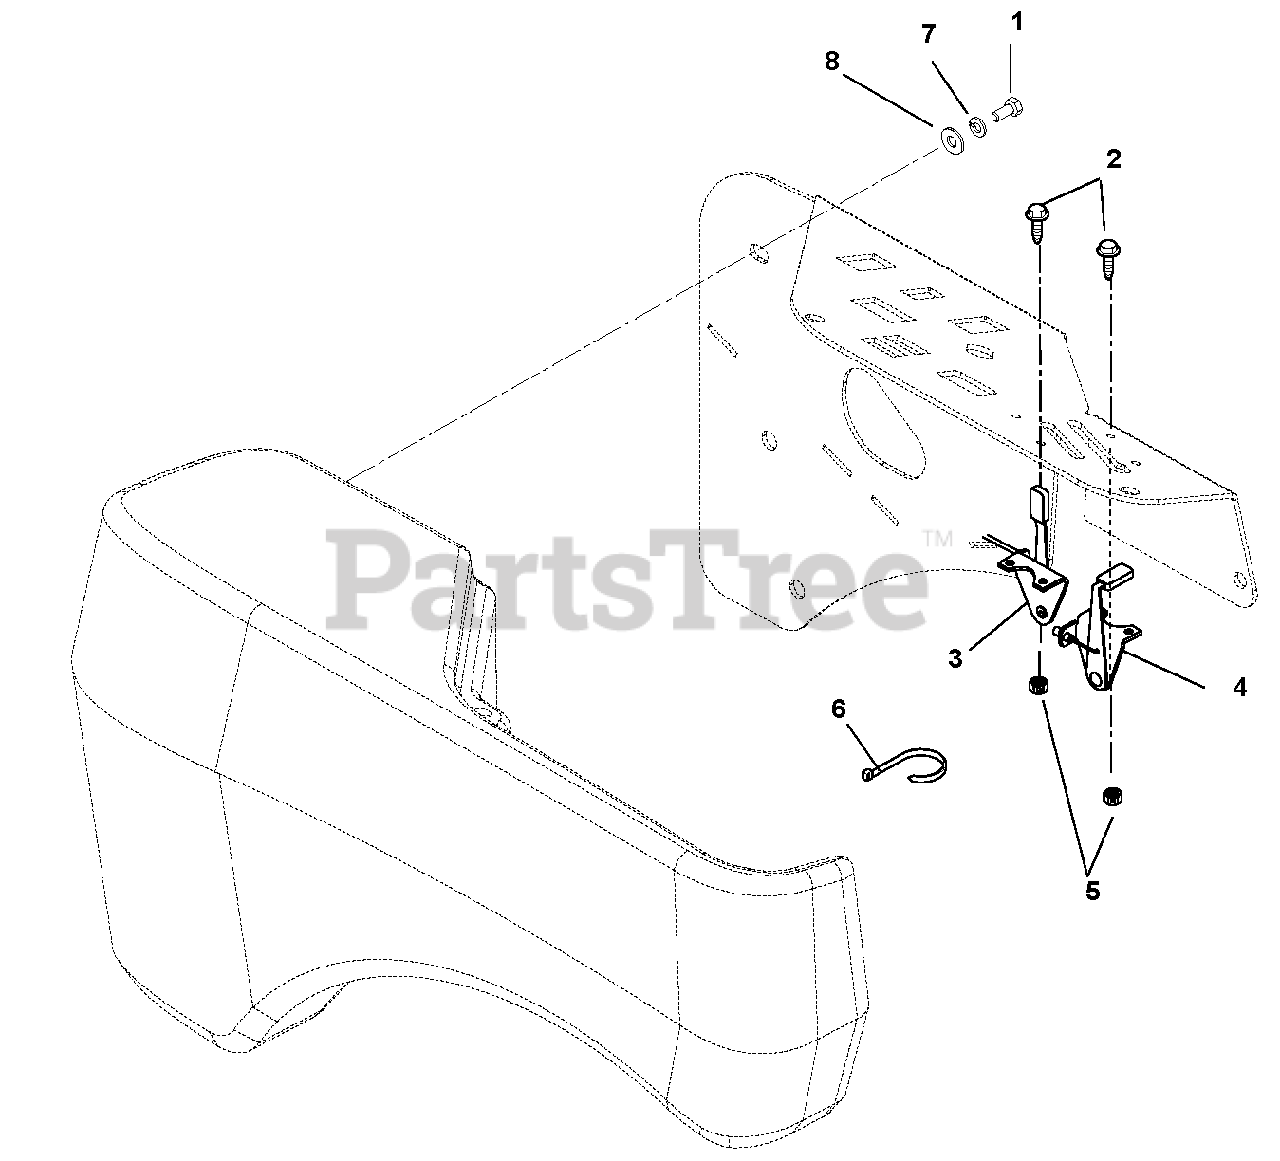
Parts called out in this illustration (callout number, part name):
1	Bolt, Hex .31-18 x .75 Grade 5 YWZC
2	Screw, Machine 10-24 x .50 Hex Washer Head
3	Cable, Kohler Throttle
4	Cable, Kohler Choke
5	Nut, Locking Nylon 10-24 With Insert
6	Cable Tie
7	Washer, Locking .31 x .078 Regular YWZC
8	Washer, Flat Steel .38 x .875 x .083 YWZC
